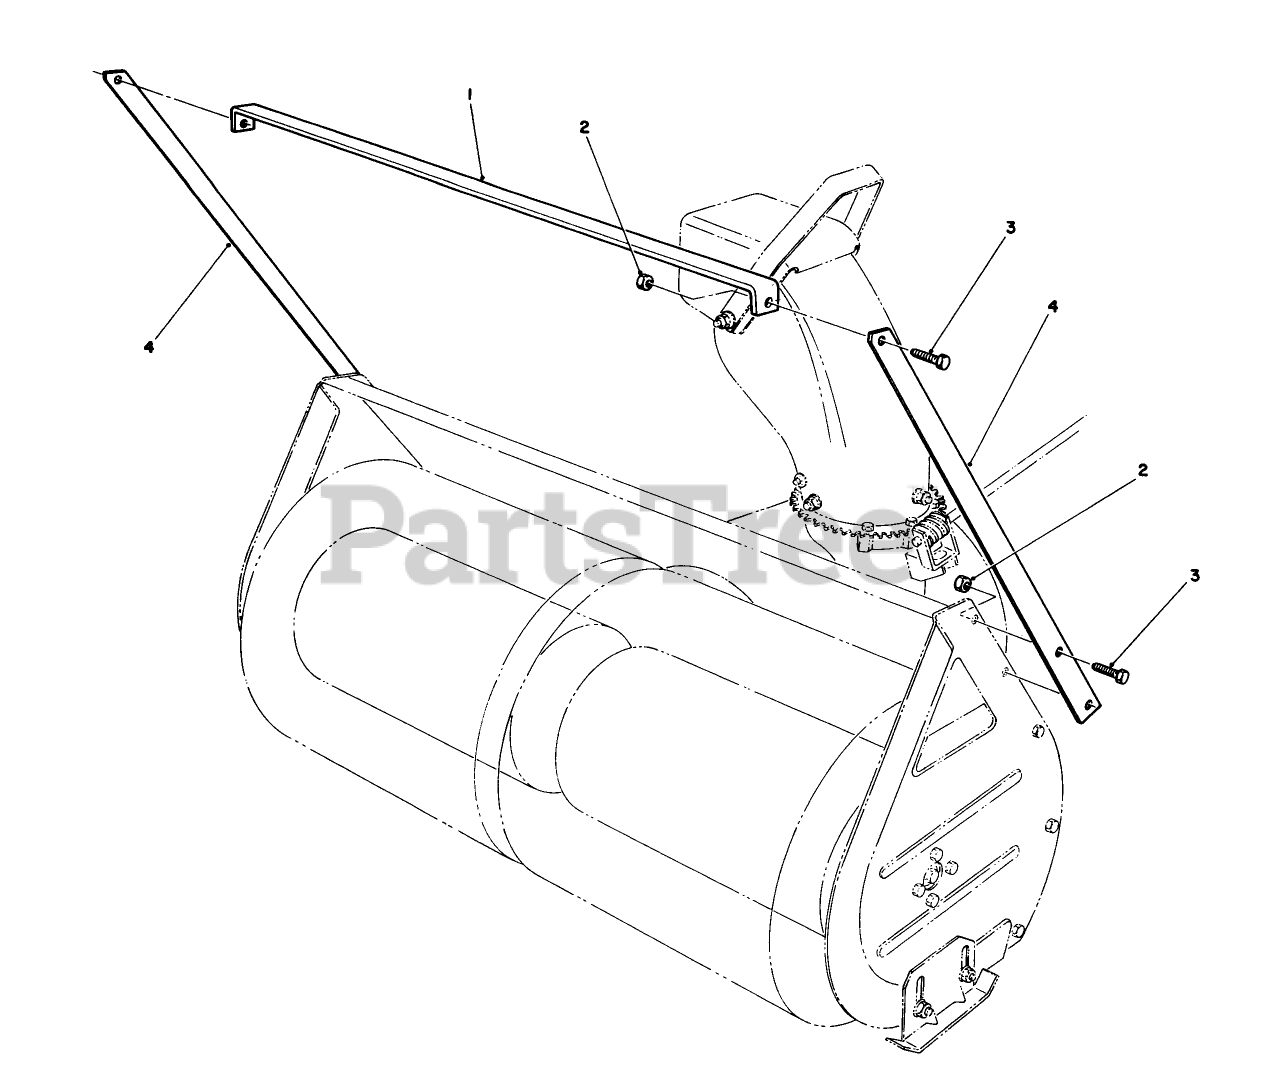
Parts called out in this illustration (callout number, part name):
1	32 TOP DRIFT BREAKER
2	NUT-LOCK, CONE
3	SCREW-HH
4	SIDE DRIFT BREAKER
